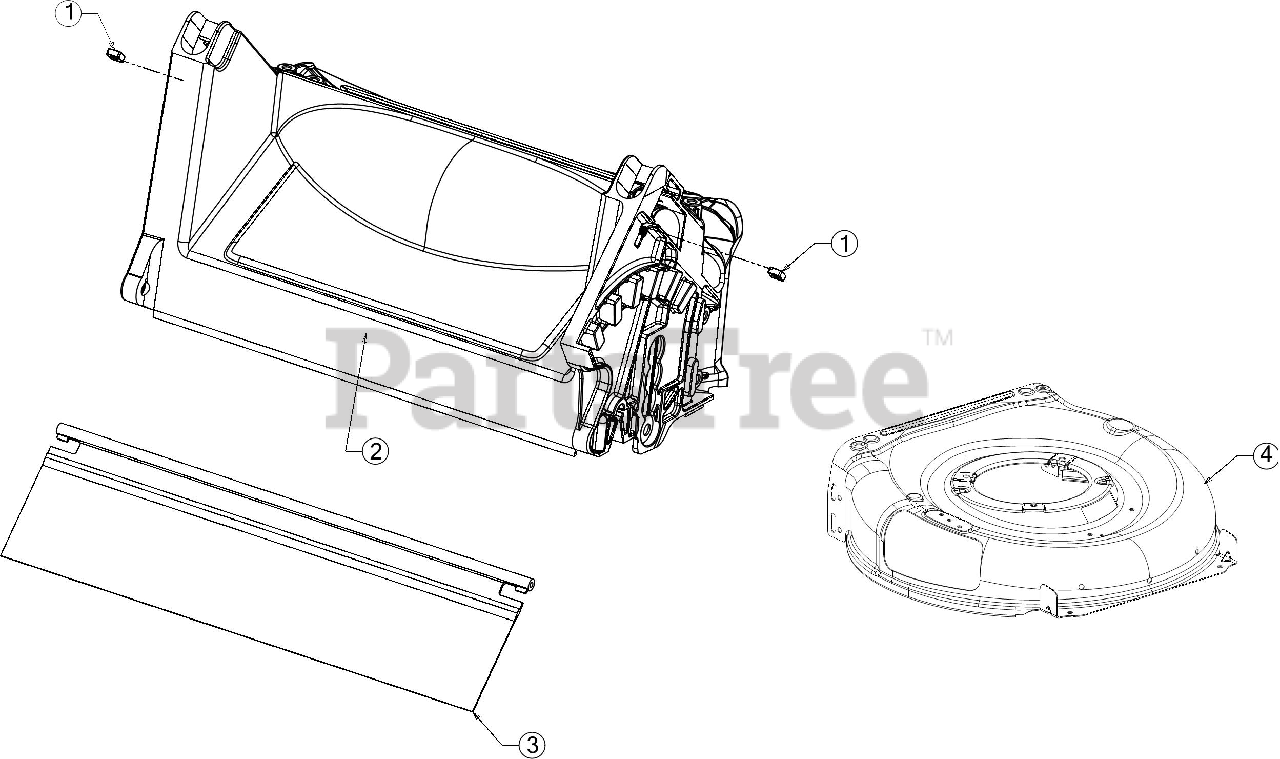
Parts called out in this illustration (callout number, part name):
1	SQUARE NUT 1/4-20
3	TRAILSHIELD
4	21" DECK (3N1)
